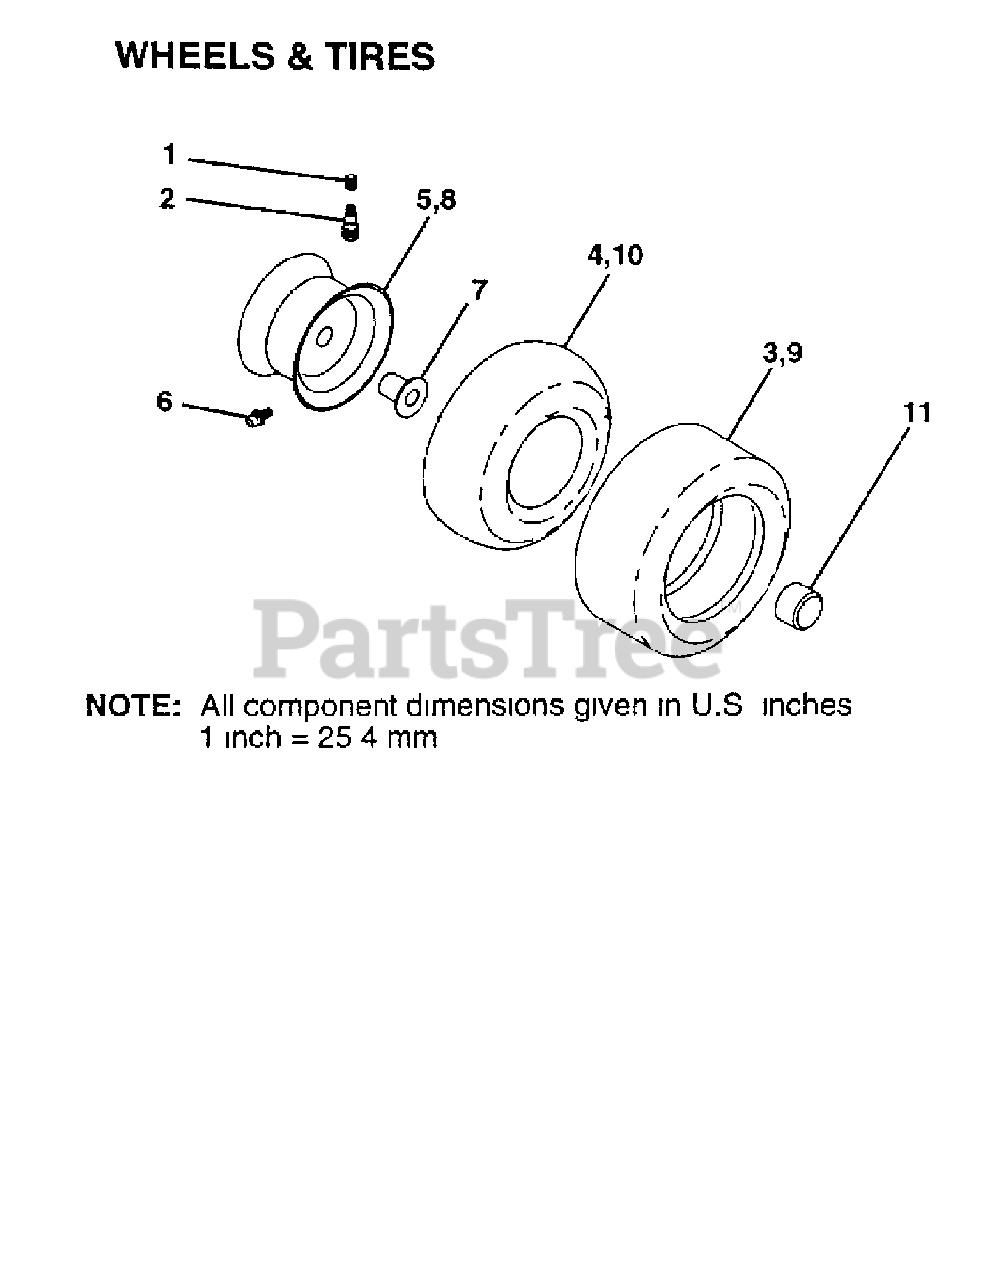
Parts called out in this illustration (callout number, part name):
1	VALVE CAP
2	VALVE STEM LT
3	TIRE HEAVY DUTY
4	TUBE.5.3/4.5/6
5	Poulan TBD
6	FITTING LT
7	BEARING T
9	Tire, .23 X 8.5-12 Turf Saver
10	TUBE.23"X9.5""X12""
11	CAP.HUB.FRONT.LT.BLACK
